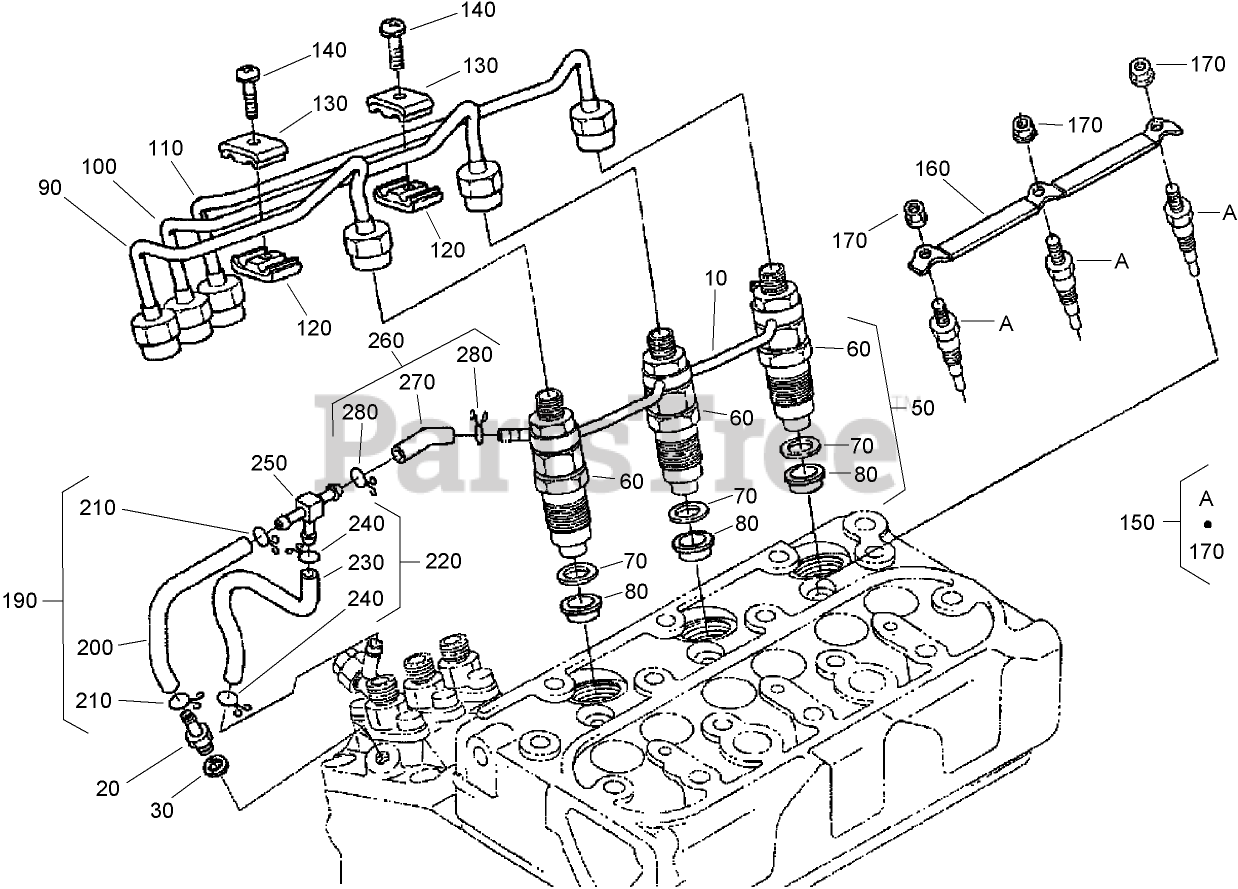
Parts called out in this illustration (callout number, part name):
10	OVER FLOW PIPE ASM
20	SCREW-BLEEDER, AIR
30	GASKET
50	NOZZLE HOLDER KIT
60	NOZZLE HOLDER ASM
70	GASKET
80	SEAL-HEAT
90	PIPE-INJECTION
100	PIPE-INJECTION
110	PIPE-INJECTION
120	CLAMP-PIPE
130	CLAMP-PIPE
140	SCREW (W/WASHER)
150	PLUG-GLOW
160	CORD-PLUG, GLOW
170	NUT-FLANGE
190	FUEL TUBE ASM
200	TUBE-FUEL
210	CLIP-PIPE
220	FUEL TUBE ASM
230	TUBE-FUEL
240	CLIP-PIPE
250	JOINT-T PIPE
260	FUEL TUBE ASM
270	TUBE-FUEL
280	CLIP-PIPE
